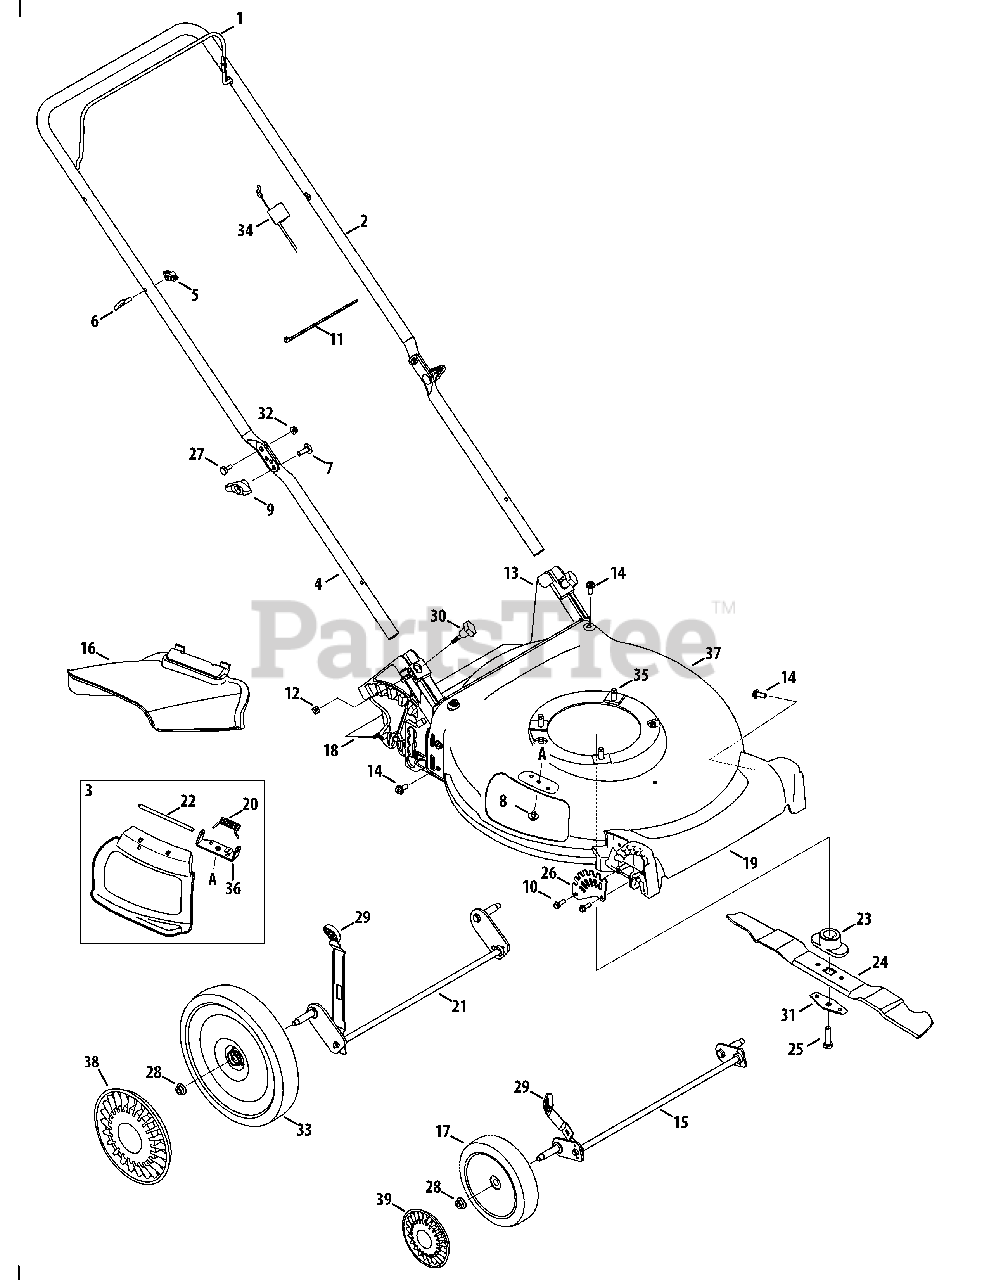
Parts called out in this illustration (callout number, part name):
1	Blade Control
2	Upper Handle, Adjustable
3	Hinged Mulch Plug Assembly
4	Lower Handle
5	Wing Nut
6	Rope Guide
7	Carriage Screw ,5/16-18
8	Screw, 1/4-20 x .500
9	Wing Knob
10	Screw, 1/4-15 x .750
11	Cable Tie
12	Nut, Sq., 1/4-20
13	Rear Baffle
14	Screw, 5/16-14 x .750
15	Front Axle Assembly
16	Side Chute
17	Front Wheel, 7 x 2 Black
18	Trail Shield
19	Front Cover
20	Torsion Spring
21	Rear Axle Assembly
22	Hinge Pin
23	Blade Adapter
24	Mulching Blade
25	Screw , 3/8-24 x 1.50
26	Front Height Adjuster Plate
27	Sldr. Screw, .375 x .126 x 1/4-20
28	Flange Lock Nut, 3/8-16
29	Adjustment Lever Knob
30	Wing Nut
31	Blade Bell Support
32	Nut, Flange Lock, 1/4-20
33	Rear Wheel, 11 x 2 Black
34	Control Cable 37.58"
35	TT Sems Screw, 3/8-16 x 1.0
36	Chute Deflector Bracket
37	Deck - 21" - Orange
38	Hubcap, 11"
39	Hubcap, 7" w/o snaps
